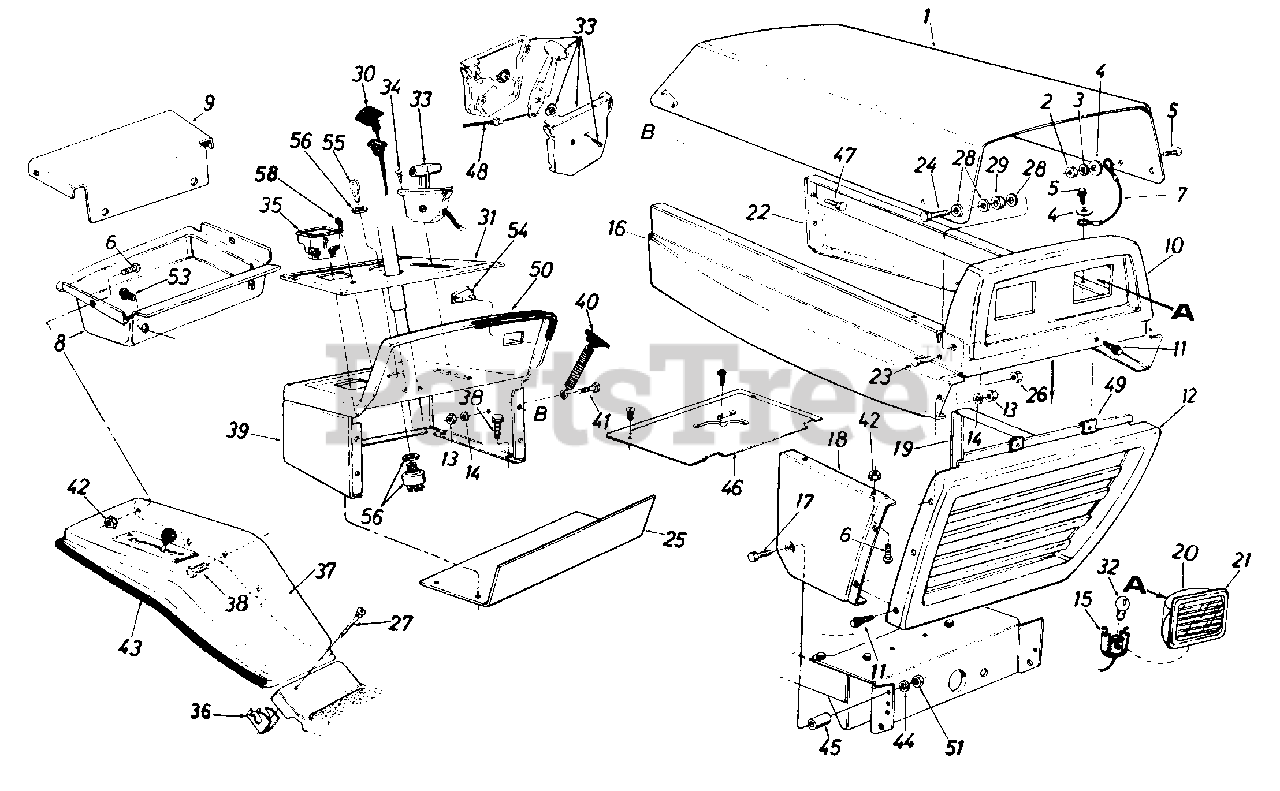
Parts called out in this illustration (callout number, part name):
3	L-Wash. #10 I.D.
4	Fl-Wash. .25" I.D. x .62"
5	Truss Scr. #10-24 x .375"*
6	Truss Hd. Scr. #10-24 x .50"*
7	Hood Stop
8	Tool Tray
11	Hex AB-Tap Scr. #10 x .50"
14	L-Wash. 1/4" I.D.*
15	Twist Lock-Lamp Socket
16	Side Panel-R.H.
17	Hex Bolt 5/16-18 x 1.50"*
18	R.H. Lower Side Panel
19	L.H. Lower Side Panel
20	Headlight Housing
21	Headlight Lens
22	Side Panel-L.H.
23	Hex Bolt 1/4-20 x .62" Lg.
24	Hex Bolt 3/8-16 x 1.00" Lg.
25	Fuel Tank Support
26	Hex Cent. L-Nut 3/8-16 Thd.
27	Carriage Bolt 1/4-20 x 2.00"*
28	Fl-Wash. .380" I.D. x 1.00"
29	Rubber Washer
30	Choke Control
31	Dash Panel Insert
32	Head Lamp
33	Throttle Box Ass'y.
34	Truss Mach. AB-Tap Scr. #10 x .5" Lg.
35	Ammeter
36	Fender Clamp
39	Dash Panel Ass'y.
40	Hood Latch Ass'y.
41	Hex Bolt 1/4-20 x .50" Lg.*
42	Hex Sems Nut #10-24 Thd.
43	Trim Strip-57" Lg.
44	Belleville Wash. .34" I.D.
45	Spacer
46	Shift Cover
47	Hex Wash. Hd. AB-Tap Scr. 1/4-20 x .62
48	Throttle Control Wire
49	Speed Nut #10Z
50	Trim Strip-15"
51	Hex Nut 5/16-18 Thd.*
53	Hex AB-Tap Scr. 5/16-18 x .75"
54	Light Switch
55	Ignition Key
56	Ignition Switch
58	Hex AB-Tap Scr. #8 x 5" Lg.
